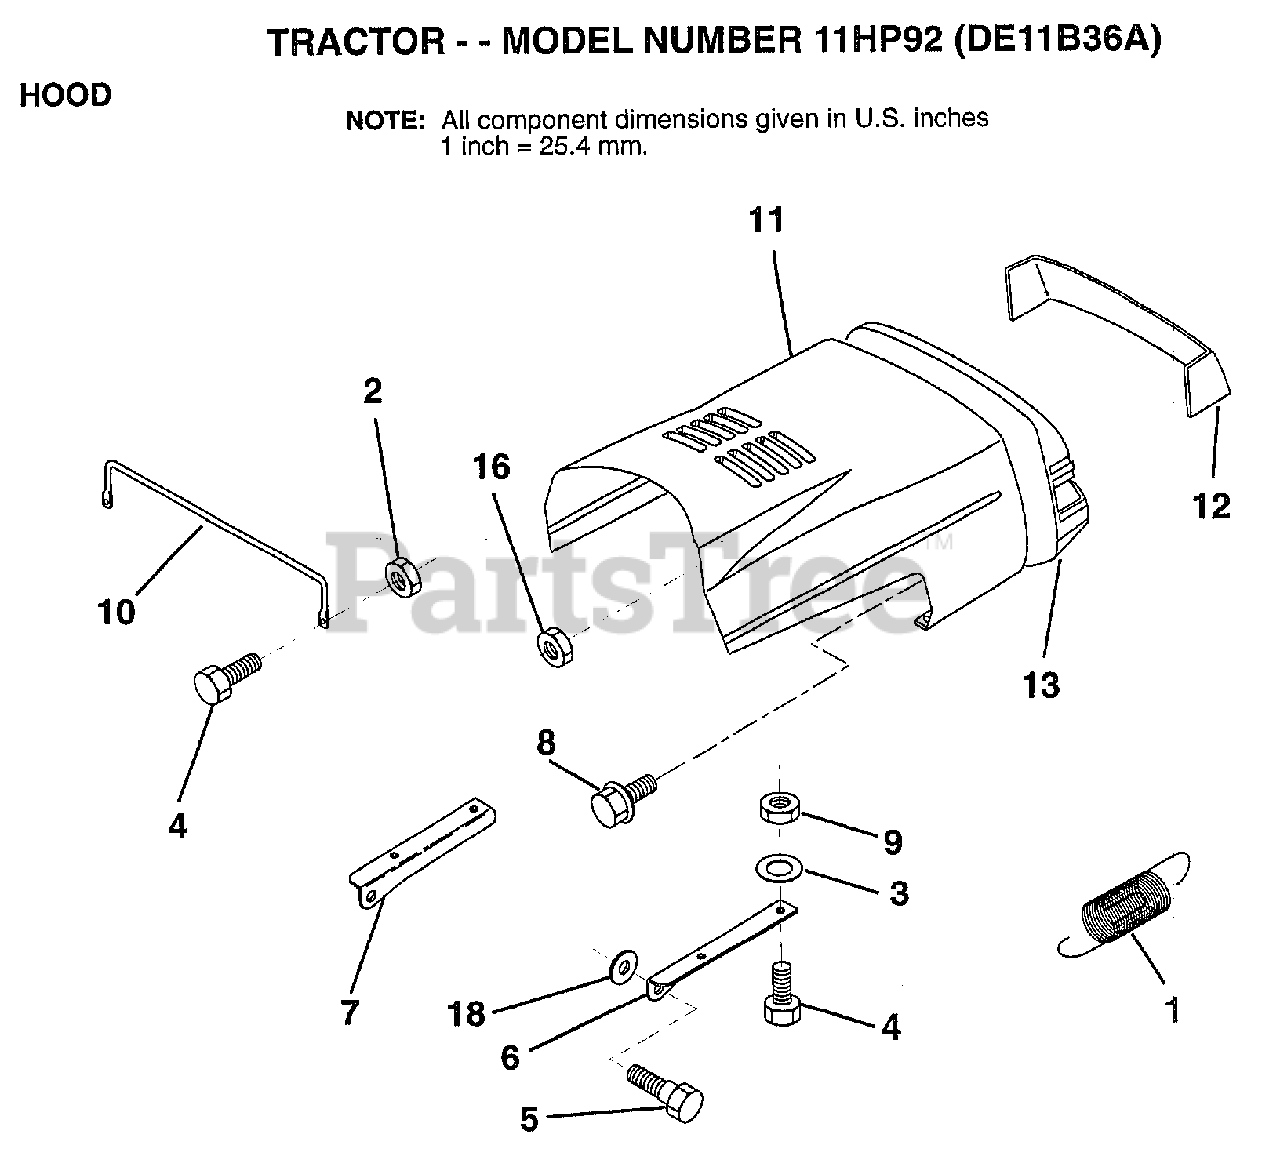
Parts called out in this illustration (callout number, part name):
1	EXT SPRING
2	NUT
3	WASHER
5	BOLT.SHLD.5/16-18
6	BRKT HOOD RH
7	BRKT HOOD LH
8	"SCREW,HWHD.HI-LO#13-16X3/4"
9	NUT
10	"BRACE,HOOD"
12	LENS.HEADLIGHT.BAR
13	GRILL
16	NUT
18	WASHER
